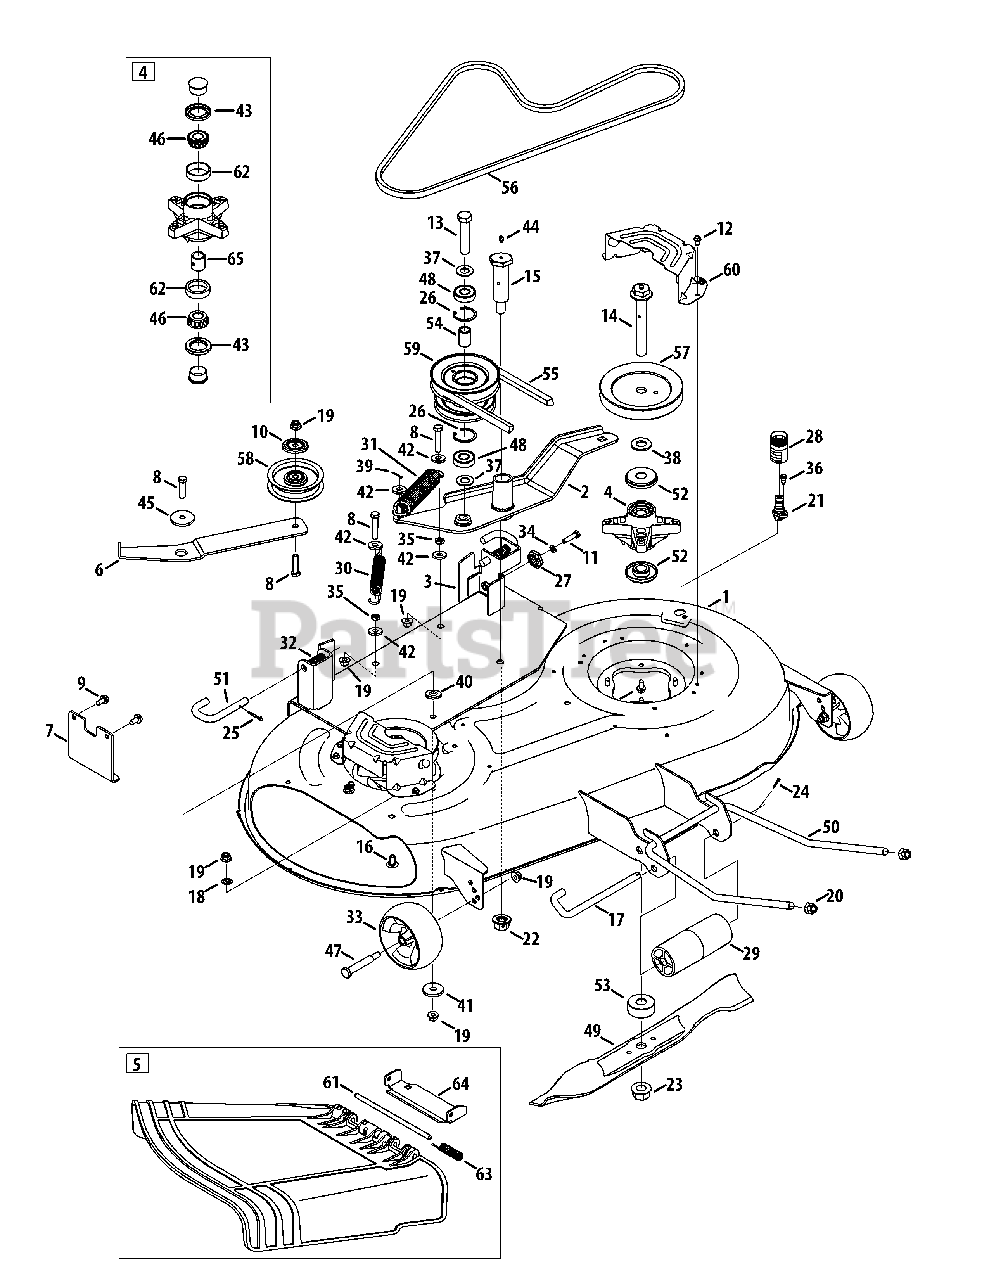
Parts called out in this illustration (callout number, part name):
3	Hanger Adjustment Bracket
4	Spindle Assembly
5	Chute Ass’y, Deflector 42" Offset
6	Idler Bracket
7	Up-Stop Front Bracket
8	Hex Screw, 3/8 x 16 x 1.75
9	Hex Washer Screw, 5/16-18 x .750
10	Pulley Cap
11	Hex Screw, 5/16-18 x 1.25
12	Hex Washer Screw, 1/4-20 x .500
13	Hex Screw, 5/8-18 x 3.00
14	Spindle Bolt, 3/4-16 x 5.37
15	Shoulder Screw, 1.0 x 3.00
16	Carriage Bolt, 3/8-16 x 1.00
17	Roller Pin, 1/2 x 7.31
18	Push Nut, 3/8
19	Flange Lock Nut, 3/8-16
20	Hex Nut, 1/2-13
21	Deck Wash Nozzle
22	Flange Lock Nut, 5/8-18
23	Flange Lock Nut, 3/4-16
24	Cotter Pin, 3/32 x 1.25
25	Cotter Pin, 5/32 x 1.25
26	Retainer Ring
27	Deck Adjustment Gear
28	Water Nozzle Adapter
29	Front Roller
30	Extension Spring, .850 x 6.415
31	Extension Spring, 1.25 x 6.9
32	Compression Spring, .66 x 1.8
33	Deck Wheel, 5.0
34	Lock Washer, 5/16
35	Jam Nut, 3/8-16
36	Shoulder Screw, 1/4-20 x 0.50
37	Flat Washer, .65 x 1.25 x .075
38	Flat Washer, .760 x 1.50 x .120
39	Cotter Pin, 3/32 x .75
40	Flat Washer, .385 x 1.0 x .030
41	Flat Washer, .45 x 1.5 x .172
42	Flat Washer, .385 x 1.00 x .135
44	Drive Lube Fitting, 3/16
45	Shoulder Spacer, .8840 x .190
46	Cone Bearing, .750
47	Shoulder Screw, 1/2 x 2.50
48	Ball Bearing, .625 x 40 x 12
49	2-in-1 Blade, 21.23
50	Front Lift Rod
51	Mower Support Pin
52	Deck Spindle Spacer
53	Spacer, .760 x 2.000 x .790
54	Spacer, .88 x .635 x 1.25
58	Idler Pulley
59	Double Pulley
60	Belt Cover
62	Bearing Cup, .750
63	Torsion Spring, .44 x 2.0
64	Chute Bracket
65	Bearing Spacer, .78 x 1.0 x 1.0425
